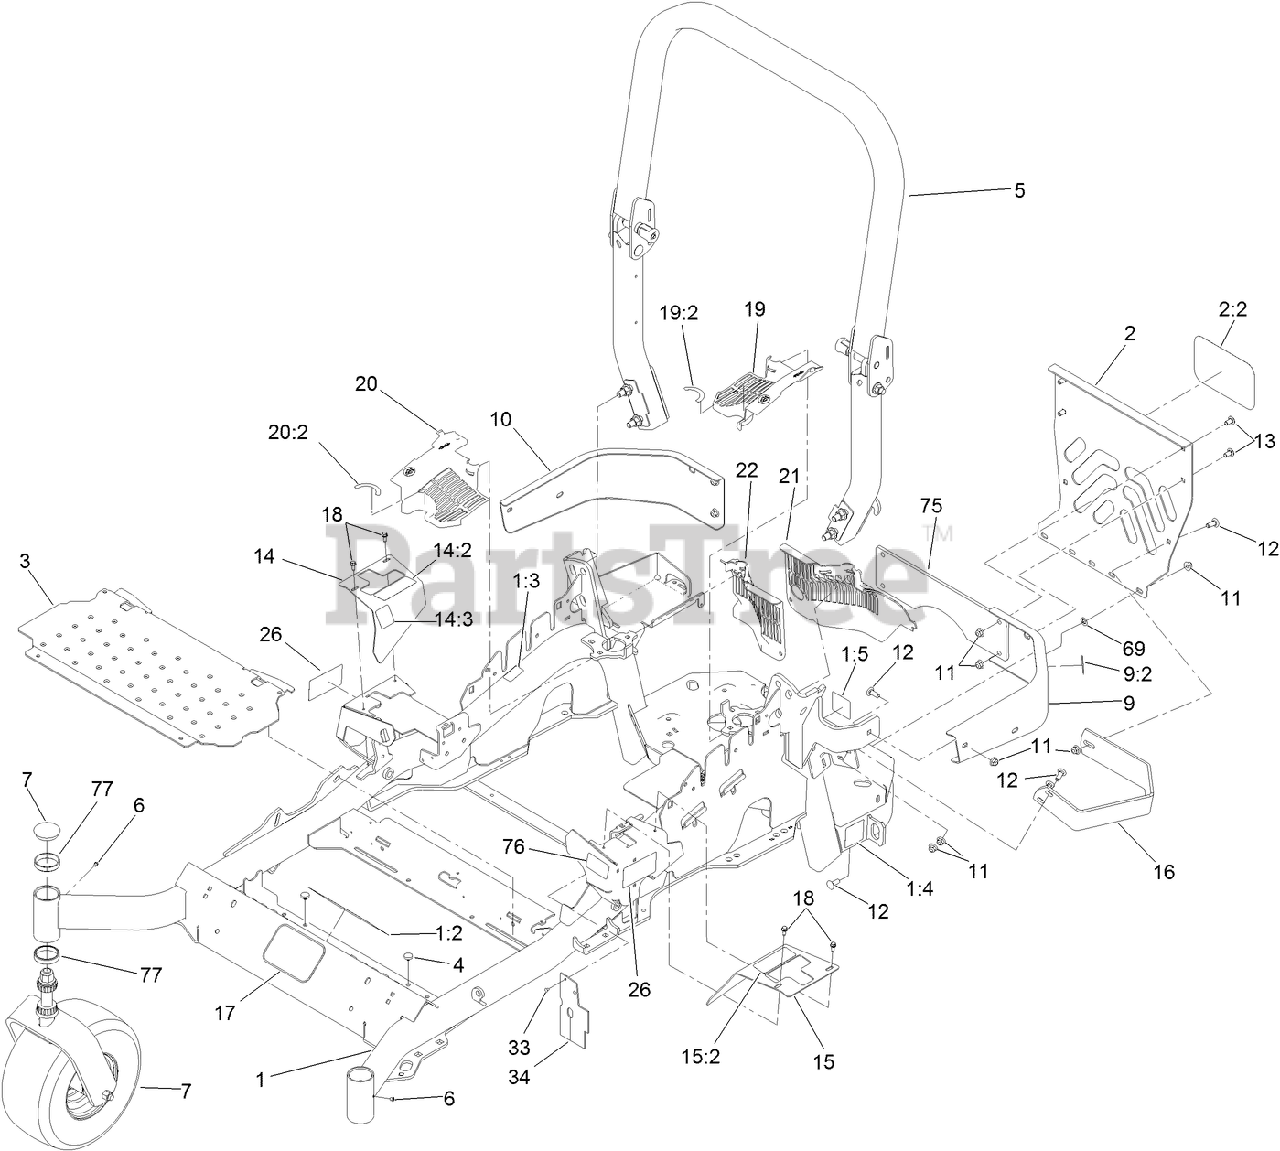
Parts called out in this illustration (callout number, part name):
1	MAINFRAME ASM
1:2	DECAL-WARNING
1:3	DECAL-DANGER SLOPE W/ROPS
1:4	DECAL-HAZARD, PINCHED FINGER
1:5	DECAL-SPARK ARRESTER
2	REAR GUARD ASM
2:2	DECAL
3	FLOORPAN
4	BUMPER
5	ROPS ASM
7	Caster Wheel ASM
9	LH BUMPER ASM
9:2	DECAL-WARNING
10	BUMPER-RH
11	NUT-HF, NI
12	SCREW-CARR
13	SCREW-CARR
14	RH MOTION CONTROL COVER ASM
14:2	DECAL-CONTROL, MOTION
14:3	DECAL-PARK BRAKE, CE
15	LH MOTION CONTROL COVER ASM
15:2	DECAL-CONTROL, MOTION
16	GUARD-MUFFLER
17	DECAL
18	SCREW-HWH
19	LH HYDRO GUARD ASM
19:2	DECAL-OIL, HYDRO
20	RH HYDRO GUARD ASM
20:2	DECAL-OIL, HYDRO
21	GUARD-HYDRO, REAR (LH)
22	GUARD-HYDRO, REAR (RH)
33	RIVET-POP
34	DEFLECTOR-AIR FLOW
69	NUT-PUSH
75	WEIGHT-PLATE, 6 LB
76	DECAL-FUEL FILL, CE
77	CUP-BEARING
